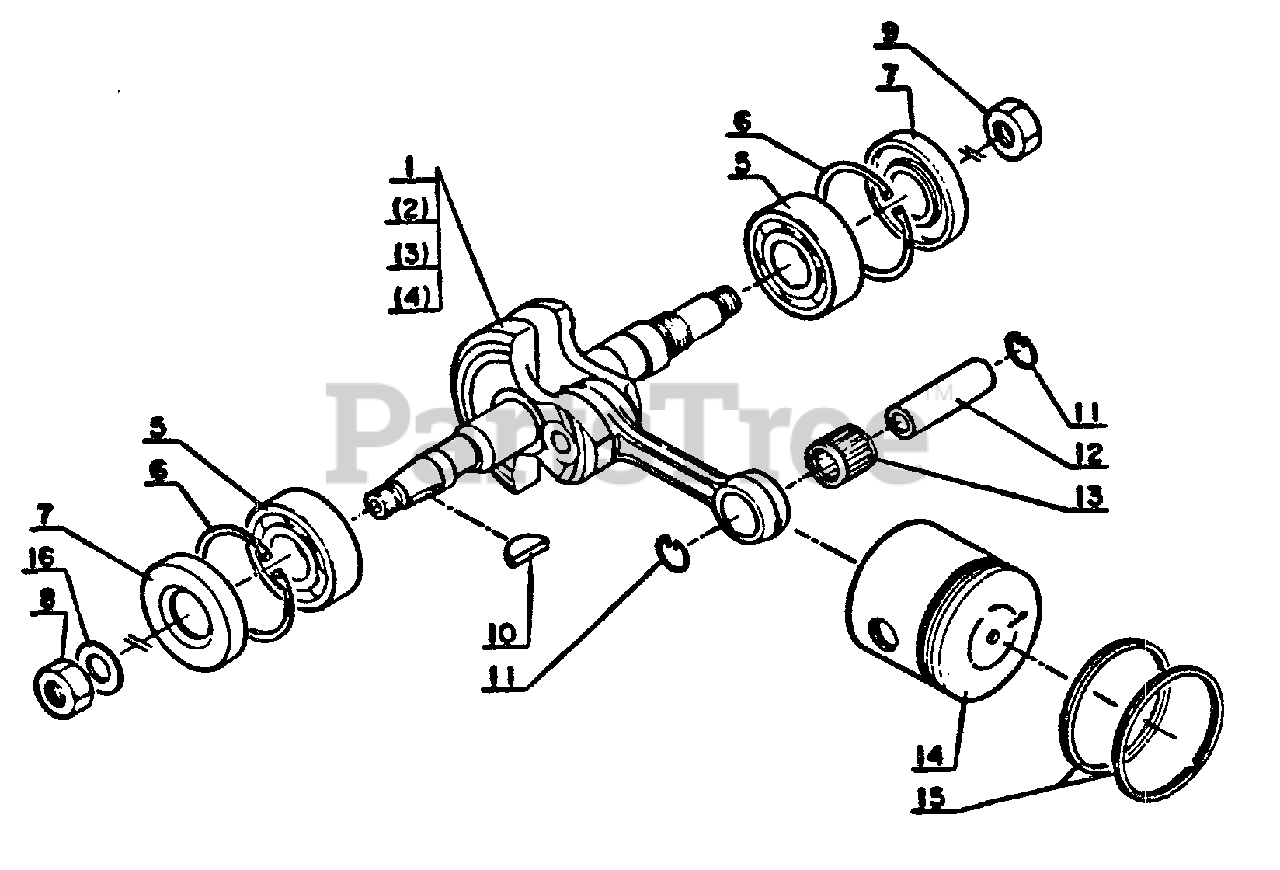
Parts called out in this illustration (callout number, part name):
1	CRANKSHAFT ASSY
5	BEARING, BALL - 6202
6	RING, RETAINING - 35
7	SEAL, OIL
9	LOCKNUT
11	RING, RETAINING - 8
12	PIN, PISTON
13	BEARING, NEEDLE
14	PISTON
15	RING, PISTON
16	WASHER - 8
